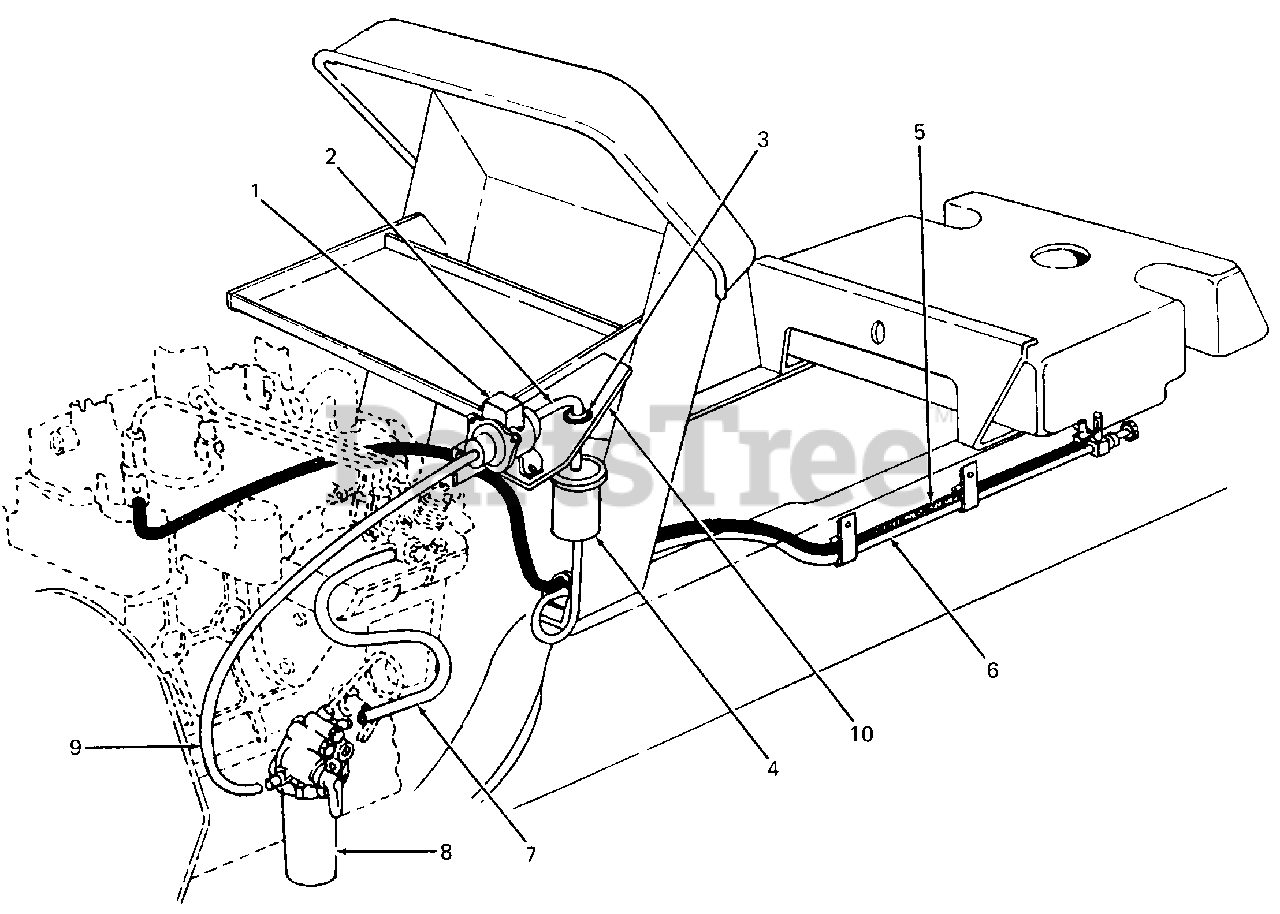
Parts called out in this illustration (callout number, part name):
1	Pump, Electric Fuel
2	Line, Fuel Pre-Filter to Electric Pump - 4.5 " Lg
3	Bushing, Snap, 3/4 ID
4	Pre-Filter, Fuel
5	Line, Fuel Engine to Tank Return - 72.5" Lg
6	Line, Fuel Pre-Filter to Tank - 44" Lg
7	Line, Fuel Filter to Injection Pump - 8" Lg
8	Filter, Fuel
9	Line, Fuel Filter to Electric Pump - 16" Lg
10	Bracket, Fuel Pump Support
